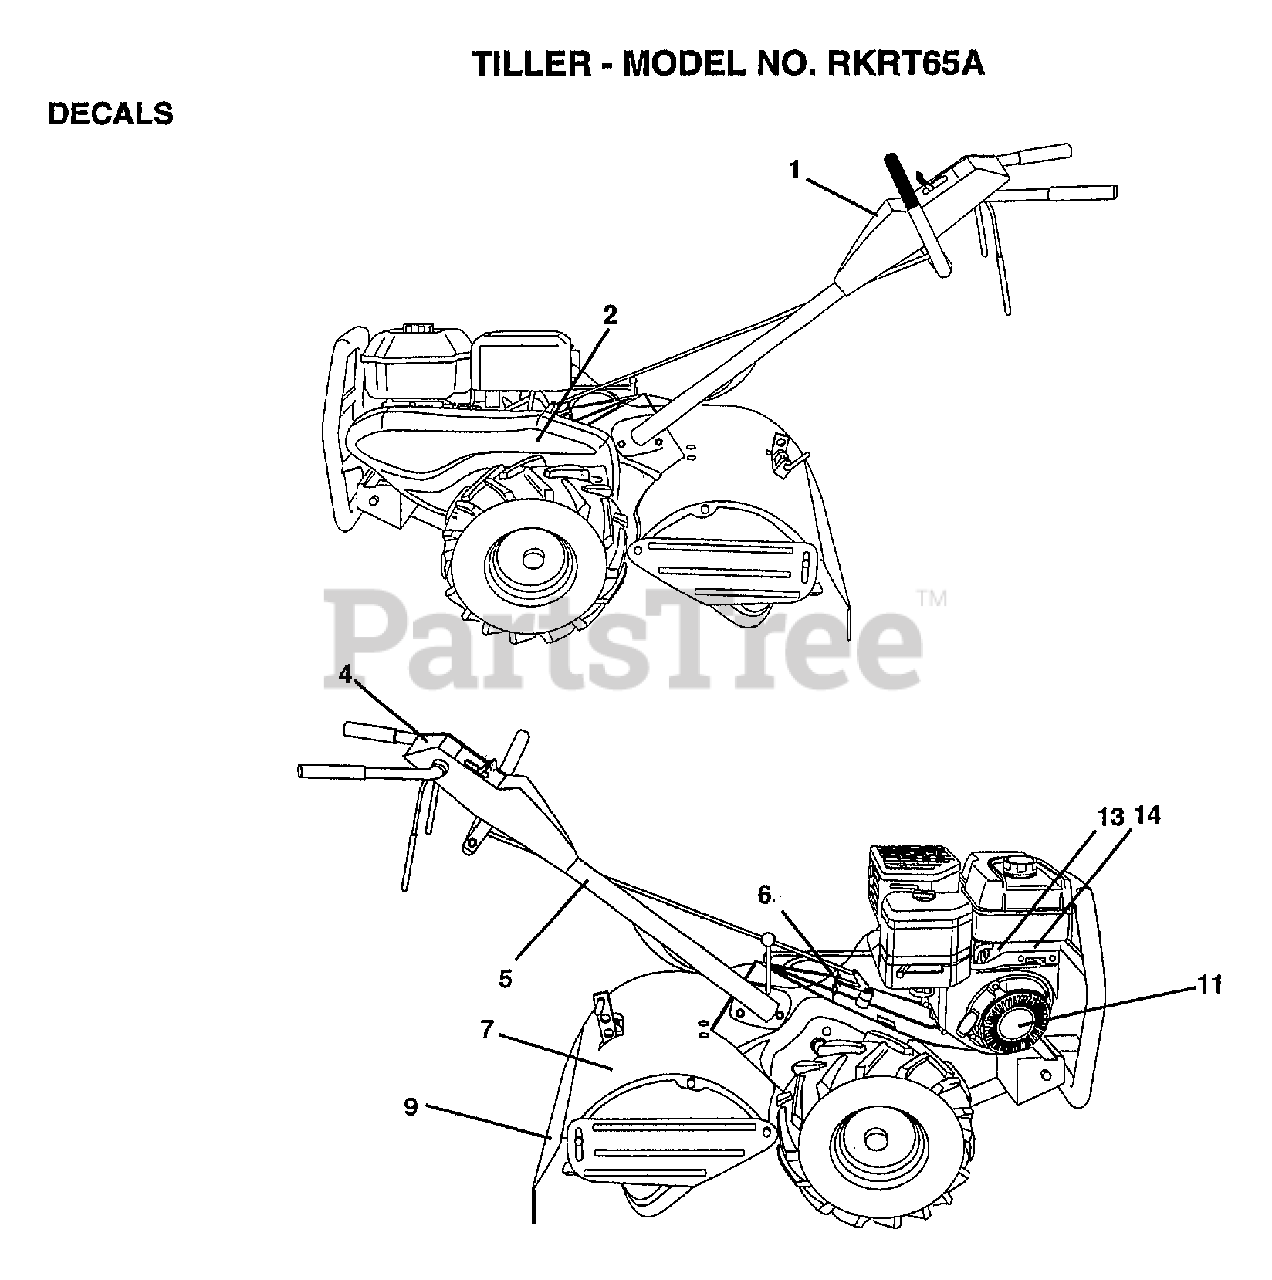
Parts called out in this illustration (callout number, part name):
1	DECAL, LOGO
2	DECAL.BH.BRG.6.5HP
4	DECAL.INSTRUCTION
5	DECAL TI
6	DECAL CRT
7	DECAL.CAUTION
13	DECAL, CHOKE
